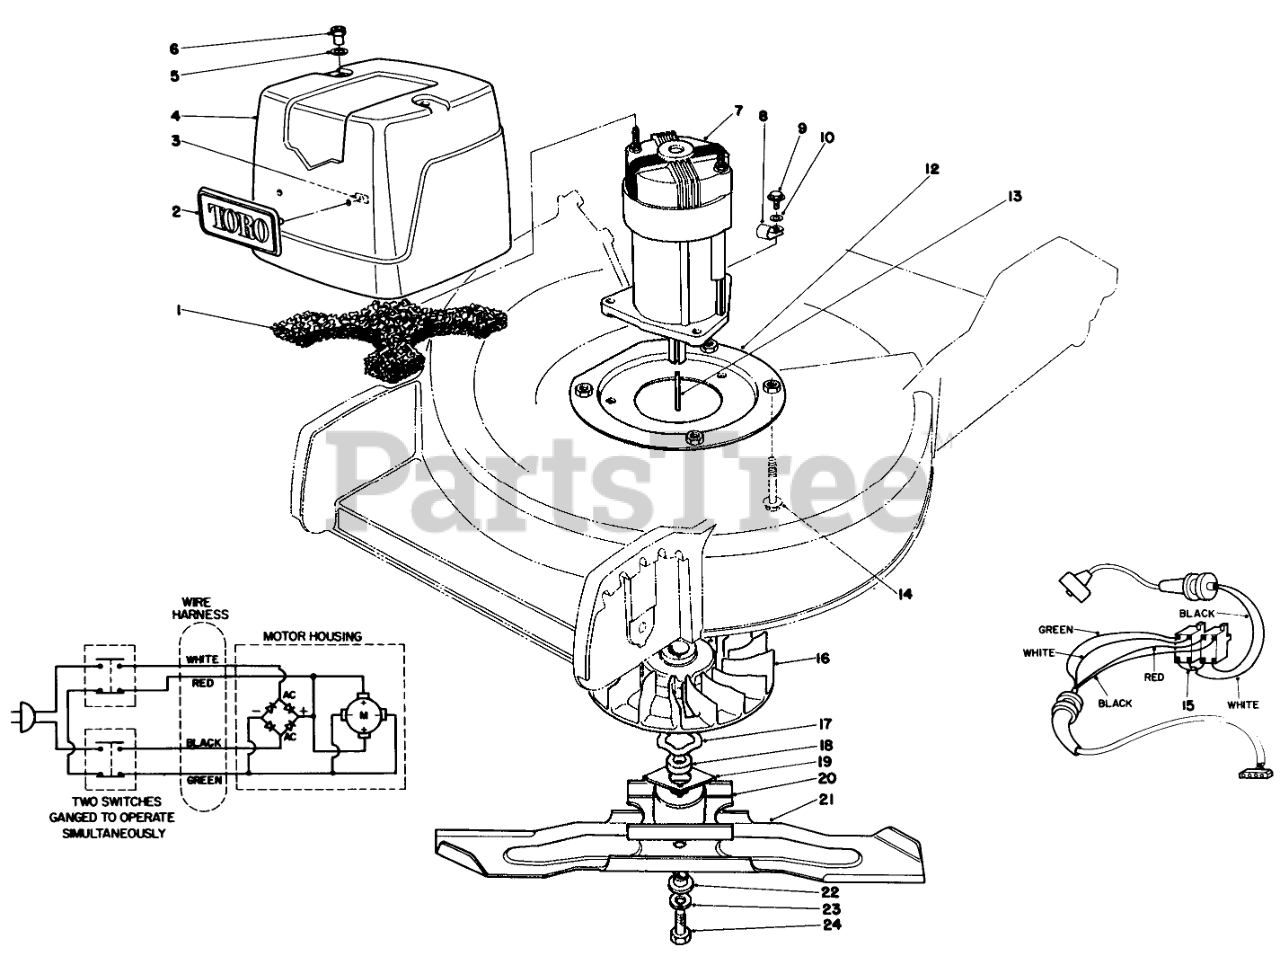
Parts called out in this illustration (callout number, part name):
1	FILTER F/W
2	TORO LOGO PLT
3	Receiver-Stud
4	Shroud-Motor
5	WASHER F/W
6	NUT F/W
7	Motor-Electric
8	CLAMP
9	SCREW-HHF
10	WASHER-FLAT
12	MOTOR MOUNT ASM WA
13	KEY-SQUARE
14	SCREW-HHF
15	BRAKE WIRE
16	FAN F/W
17	WAVE WASHER
18	BLADE RETAINER SPACER
19	FAN DRIVER
20	BLADE RETAINER WA
21	Blade
22	BLADE SPACER
23	WASHER-LOCK/SP
24	SCREW-HH
